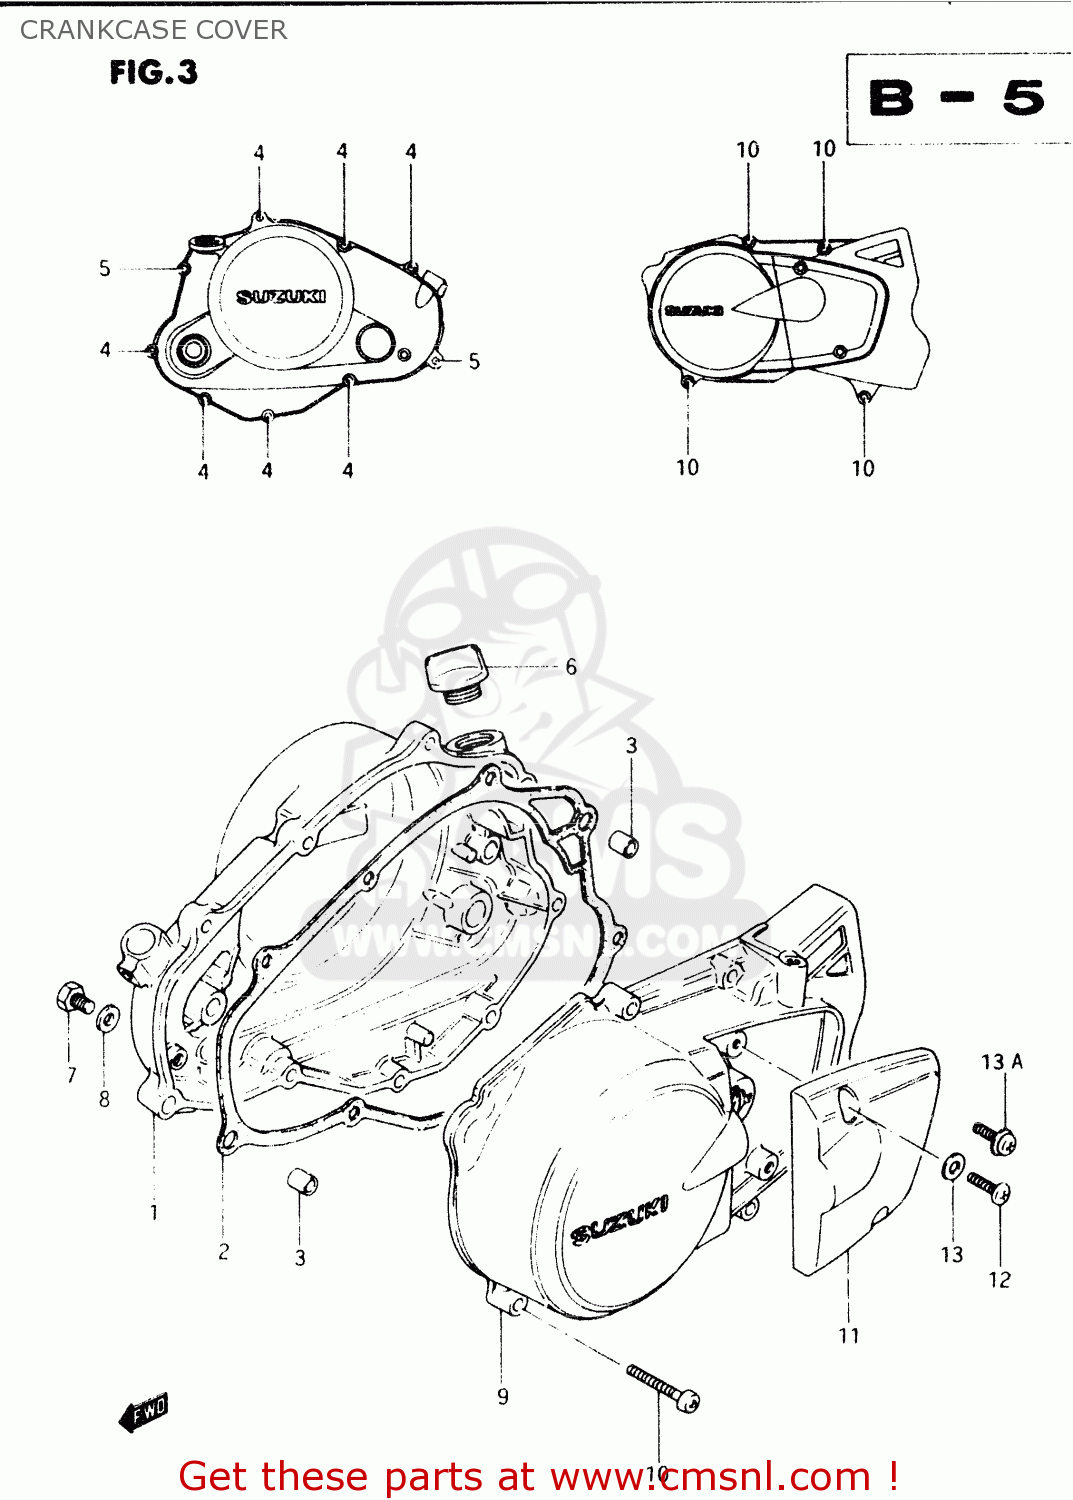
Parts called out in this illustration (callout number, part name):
1	COVER,CLUTCH
2	GASKET,CLUTCH COVER (NAS)
3	PIN
4	SCREW
5	SCREW
6	PLUG SET
7	SCREW(6X10)
8	GASKET(6.2X11X1) (NAS)
9	COVER,MAGNETO
10	SCREW
11	CAP,CLUTCH RELEASE ADJUST
12	SCREW
13	WASHER,5MM
13A	SCREW 5X12
